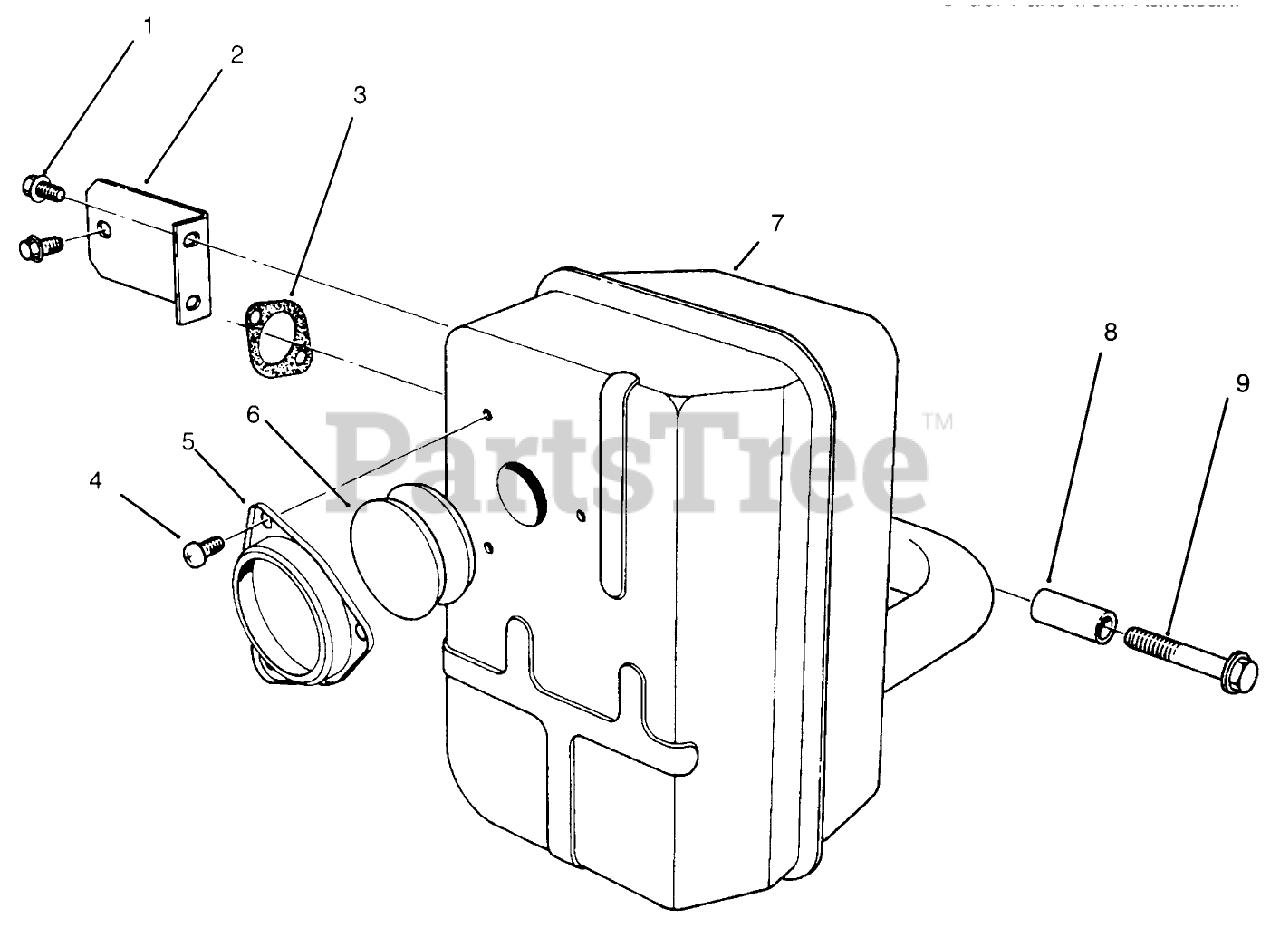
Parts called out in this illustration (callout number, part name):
1	Bolt-Flanged (8X12)
2	Bracket
3	Gasket
4	Screw
5	Cap
6	Arrester-Spark
7	Muffler Assembly (Incl. Ref.# 4,5 6)
8	Collar
9	Bolt-Flanged (8X45)
